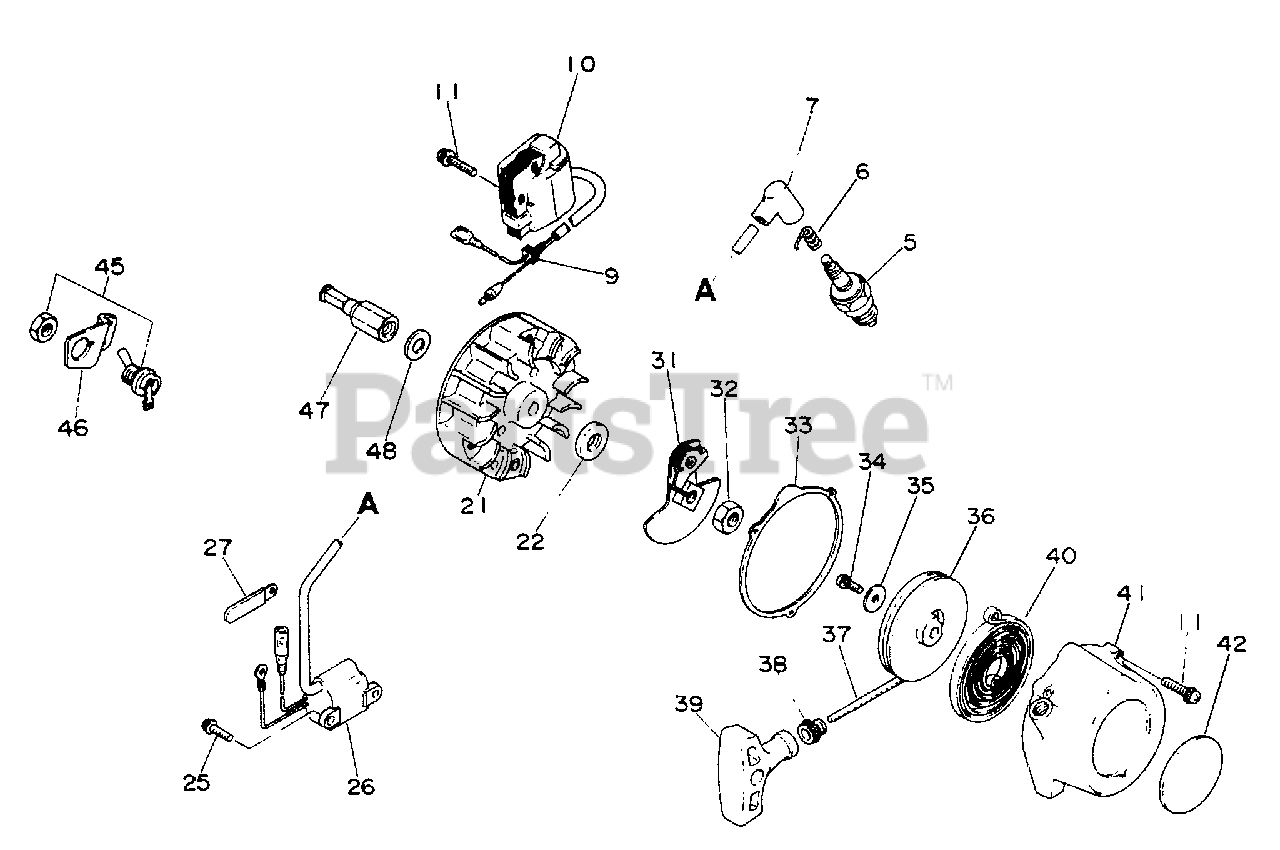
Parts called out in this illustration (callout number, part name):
5	SPARK PLUG - CJ8
6	TERMINAL, SPARK PLUG
7	CAP, SPARK PLUG
10	COIL, IGNITION
11	SCREW 4×20
21	FLYWHEEL
25	SCREW 4×14
26	COIL, IGNITION
27	CLIP
31	PAWL ASSY, STARTER
32	NUT 8×1.25
33	GASKET, STARTER
34	SCREW - 4×10
35	WASHER 4.1×15.5×1T
36	REEL, ROPE
37	ROPE, STARTER 3.0×850
38	GUIDE, ROPE
39	GRIP, STARTER
40	SPRING, RECOIL
41	CASE, STARTER
42	LABEL, ECHO
45	SWITCH, IGNITION
46	BRACKET, SWITCH
47	DRIVESHAFT
